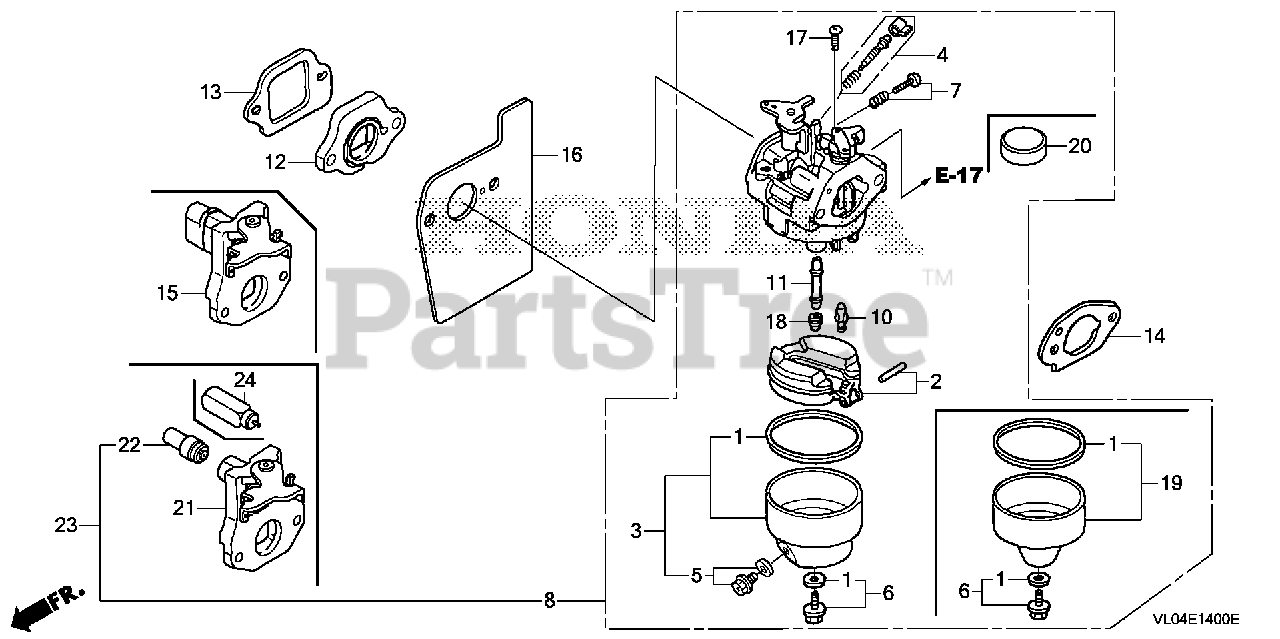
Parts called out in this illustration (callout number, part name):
1	GASKET SET
4	SCREW SET (CARBURETOR NO.)
6	SCREW SET
7	SCREW SET (THROTTLE STOP) (CARBURETOR NO.)
8	CARBURETOR ASSY. (BB62W C)
10	VALVE, FLOAT
11	NOZZLE, MAIN
12	INSULATOR, CARBURETOR
13	GASKET, INSULATOR
14	GASKET, CARBURETOR
16	GUIDE, AIR
17	SCREW, PAN (5X6)
18	JET, MAIN (#62) (CARBURETOR NO.)
18	JET, MAIN (#60) (CARBURETOR NO.)
18	JET, MAIN (#65) (CARBURETOR NO.)
19	CHAMBER SET, FLOAT (CARBURETOR NO.)
